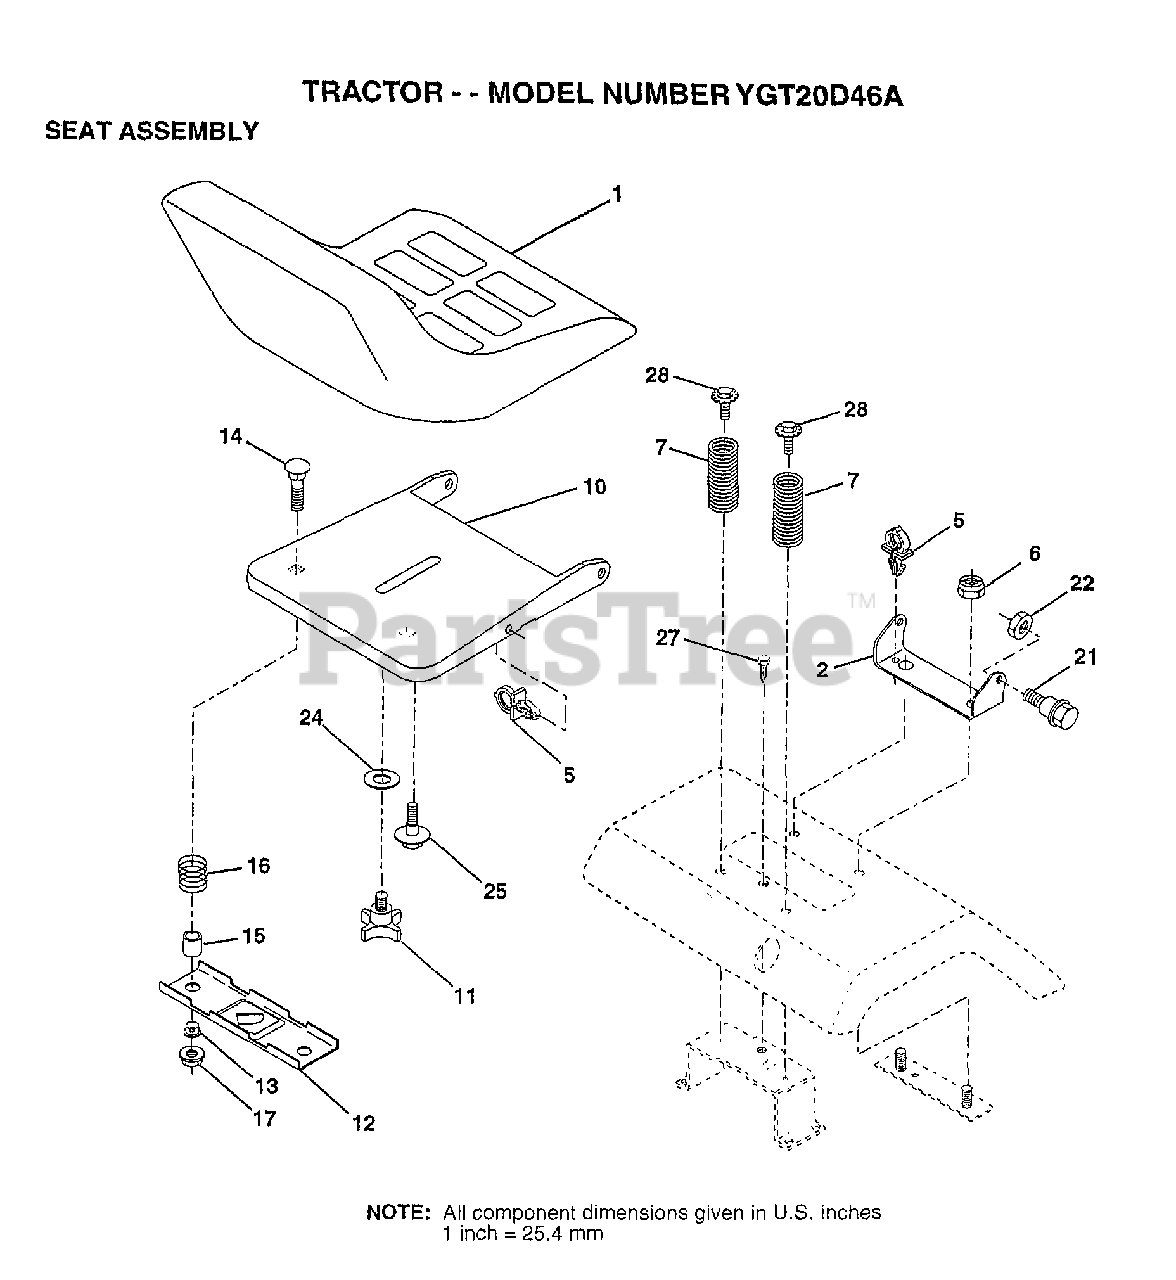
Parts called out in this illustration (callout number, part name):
2	BRACKET PVT SEAT
5	CLIP.PUSH-IN.HING
6	NUT
7	SPRING COMPRESSIO
10	PAN-SEAT
11	"KNOB 1/2"" YT"
12	BRKT SWITCH
13	BUSHING
15	SPACER SPLIT
16	SPRING COMPRESSED
21	"BOLT,SHOULDER"
24	WASHER
25	"BOLT,SHOULDER"
27	SCREW LT
28	BOLT.5/16-18.UNC
